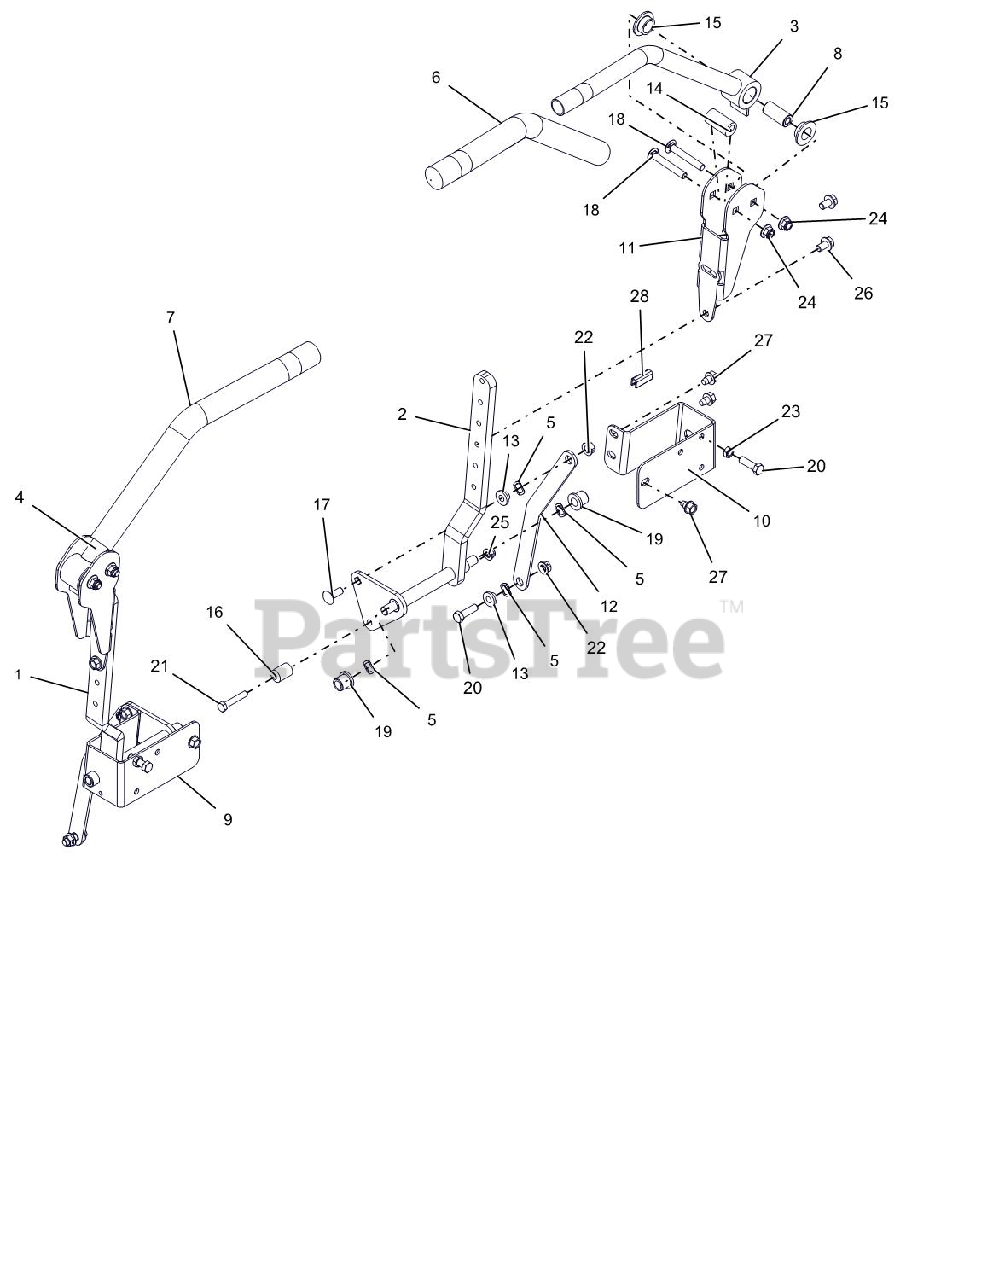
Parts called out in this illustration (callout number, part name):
1	WMT,PT/PT100RH LOWER CNTRL ARM
2	WMT,PT/PT100LH LOWER CNTRL ARM
3	WLDMT, CONTROL HANDLE- BLK
4	WLDMT, CONTROL HANDLE- BLK
5	WAVE WASHER .531X.781X.125FH
6	GRIP, HANDLEBAR
7	GRIP, HANDLEBAR
8	SPACER, STEERING ARM
9	RH PT/PT100 DRV CNTRL STOP-RED
10	LH PT/PT100 DRV CNTRL STOP-RED
11	ADJ UPPER CONTROL ARM BRKT-BLK
12	LINK, DRIVE CONTROL - BLACK
13	BSHG-FLG .385X.500X.875X.406
14	BSHG, ECCENTRIC.406X.875X1.625
15	BSHG-FLG .762X1.48X.44 NYL
16	ECCENTRIC
17	@BLT-RDHDSQNK .38-16X1.00 G5YZ
18	BLT-RDHDSQSHK, 38-16X2.50 G5YZ
19	BHSG-FLG .500X.750X.750X.125
20	@BLT-HEX .38-16X1.25 GR5 YWZC
21	@BLT-HEX .31-18X1.75 GR5 YWZC
22	NUT-LK-CTR-FLG .38-16 YWZC
23	NUT-HEX-JAM .375-16 YWZC
24	@NUT-LK-NYL-FLG .38-16 YWZC
25	@NUT-LK-NYL-FLG .31-18 YWZC
26	BLT, SCRHFWH .375-16X.625 YWZC
27	@SCR-TAP .38-16X.50 HWH TR YWZ
28	STRIP, COWL
